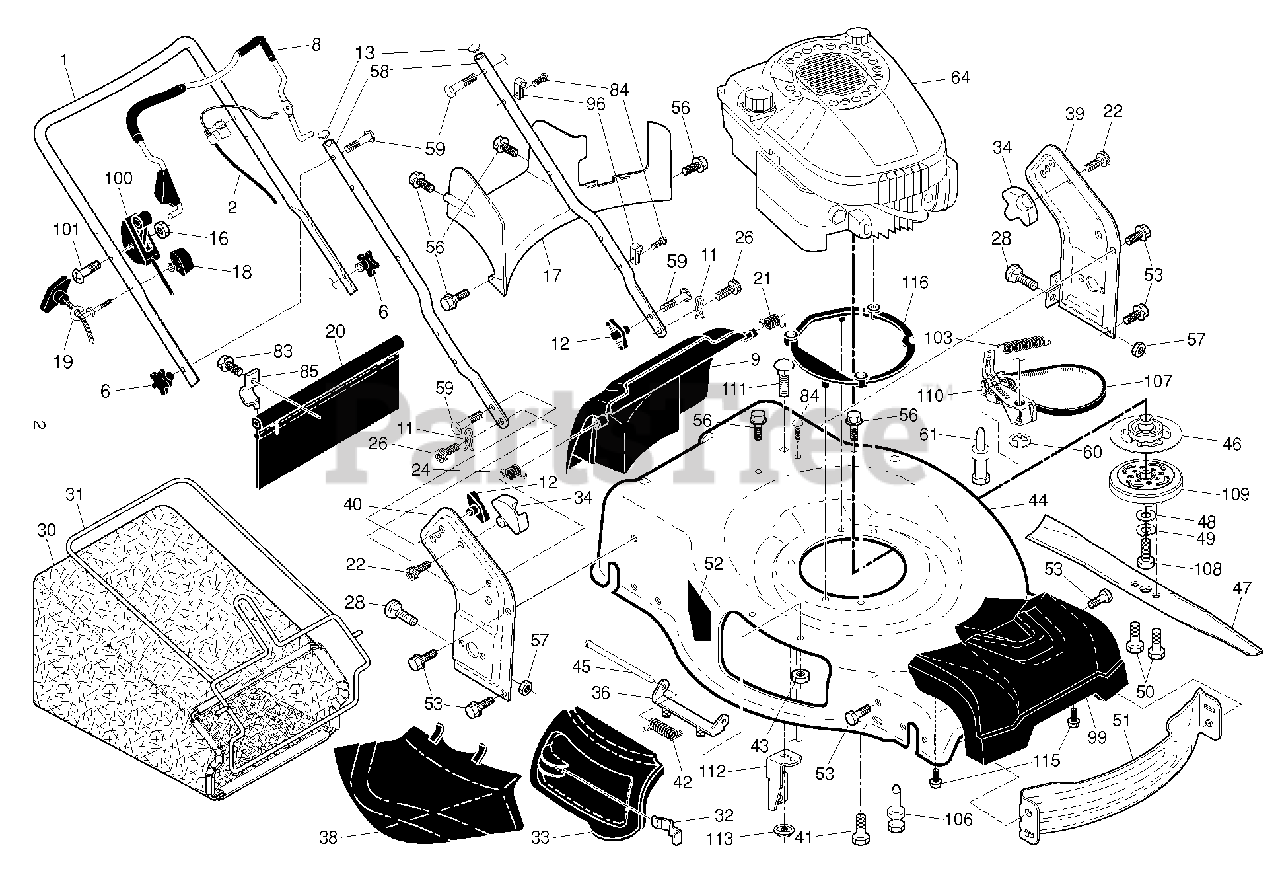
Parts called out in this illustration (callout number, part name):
1	HANDLE.UPPER.3.POS.BS.AW2.GREY
2	CABLE.BBC.22+.AW2.BS.ERGO.WALK
6	KNOB.HANDLE.PLASTIC.STAR.BLACK
8	RP.LVR ASMBBC.EN.ERGO.OM.OR/OR
9	DOOR.REAR.ASM.22+.HUSQ.FG/RGD
11	COTTER.HAIRPIN.DOOR/HANDLE.PIV
12	KNOB, DEFLECTOR
13	PLUG.PLASTIC.7/8".14-20.GAUGE
16	NUT
17	BAFFLE.REAR.22+RGD.AWD.PLASTIC
18	T-KNOB.NEW ROPE GUIDE
19	GUIDE.ROPE.BLK.ZINC.CHROM
20	SKIRT.REAR.22PLUS.RGD.LW(2 2MC
21	SPRING.LH.BLACK
22	SCREW.PAN.HEAD.#10
24	SPRING.RH.GRAY
26	SCREW,DOOR/HANDLE.PIVOT
28	BOLT.CARRIAGE.LN.5/16-18X.5/8
30	GBAG.BA85028EM.NOFRAME.GRY/SLV
31	FRAME.GBAG.22+.BLK
32	LATCH.DOOR.ZINC
33	DOOR.MULCH.22 PLUS.HUSQ.GREY
34	BRACKET.GRASSBAG.ATTACHING.BLK
36	BRACKET.ASM.HINGE.21.FWGD.
38	DEFLECTOR.CLIPPING.22.BLACK
39	BRACKET.ASM.HANDLE.LT.22+.GREY
40	BRACKET.ASM.HANDLE.RT.22+.GREY
42	SPRING.TORSION
43	NUT.HEX.FLANGE.1/4
44	HOUSING.22+AW.MC.HD.WO.BBC.STB
45	ROD.HINGE.21
46	PULLEY.BBC.DRIVING
47	BLADE.22.4-N-1.BBC.RUST PREV
48	WASHER.CRANK.BOLT
49	LOCKWASHER
50	BOLT.BLADE
51	BAFFLE.FRONT.22.PLUS
52	DANGER DECAL
53	BOLT.5/16HEX.WHS.HD
56	SCREW.HX.13X.750
57	NUT.FLANGE.5/16
58	HANDLE.LOWER.22+BT.2PC.GRY
59	BOLT, HANDLE 5/16-18X1.75
60	E-RING.12MM.SHAFT
61	BOLT.BBC.TENSION.PIVOT
83	TAPPING SCREW
84	FASTENER.PUSH.O.250X0.783
85	BRACKET.SKIRT.22+.BZP
96	CLIP.CABLE.BLK
99	COVER.ASSEMBLY.FRONT.22+AWD
100	CONTROL.THROTTLE.BBC
103	SPRING.BRAKE.RESET
106	BOLT.BRAKE.RESET.SPRING
107	BELT.COG.BBC
108	SCREW, HEX HD 3/8-24 X 1-3/8
109	HUB.FREE.BBC.ASSEMBLY(2 2MC)
110	ARM.BBC.TNSION.ARM.PULL(2 2MC)
112	BRACKET.CABLE MOUNTING.22+
113	NUT.FLANGE.1-4-20-SERR
115	SCREW.SHOULDER.5/16X1.375
116	SPACER.AWD.B&S
